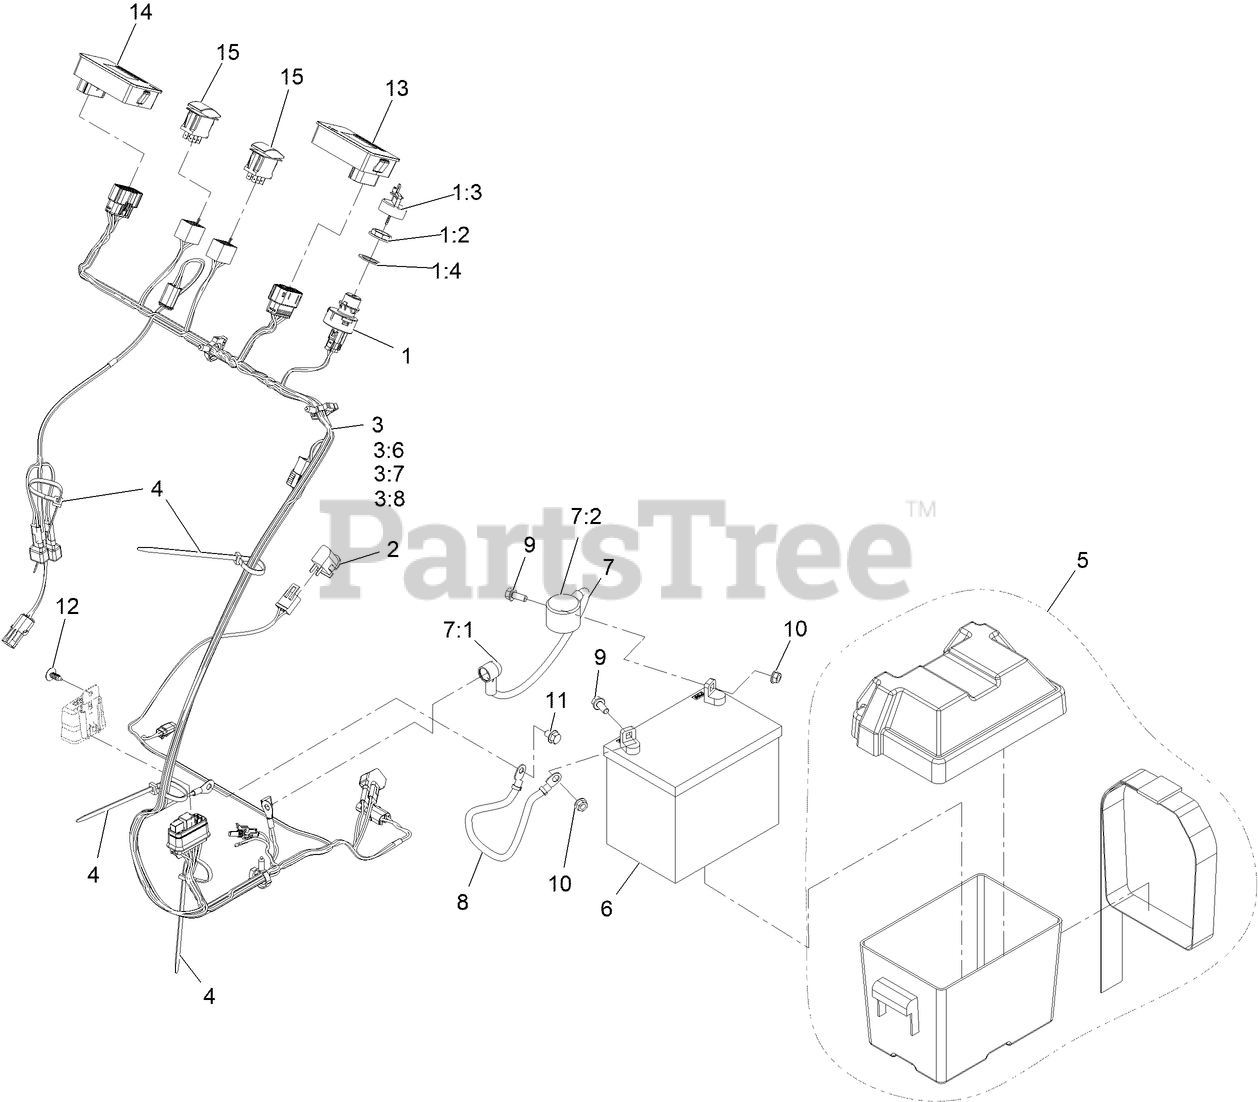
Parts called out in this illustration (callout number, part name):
1	IGNITION SWITCH ASM
1:2	NUT-MOUNTING
1:3	IGNITION KEY SET
1:4	WASHER-BACKUP
2	SWITCH-BAIL
3	HARNESS-WIRE
3:6	FUSE-MINI BLADE, 20 AMP
3:7	RELAY-MICRO
3:8	RELAY-COIL, NC, MP280
4	TIE-CABLE
5	BATTERY BOX
6	BATTERY
7	POSITIVE BATTERY CABLE ASM
7:1	INSULATOR-SOLENOID
7:2	INSULATOR-BATTERY
8	CABLE-BATTERY, NEGATIVE
9	SCREW-HHF
10	NUT-HF
11	SCREW-HHF
12	PLUG-PLASTIC
13	HOUR METER ASM
14	HOUR METER ASM
15	SWITCH
